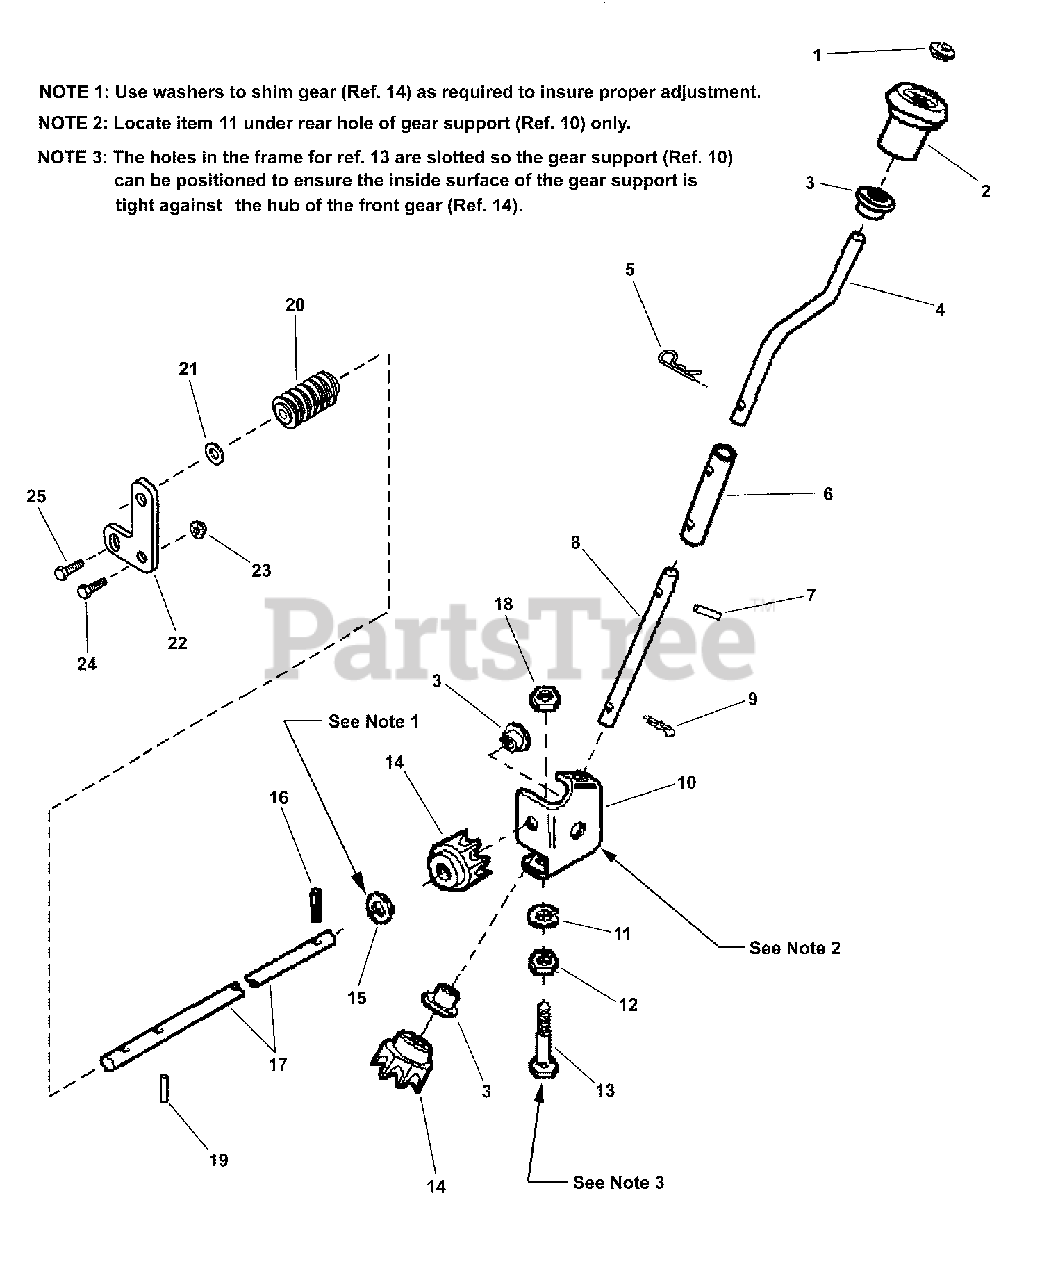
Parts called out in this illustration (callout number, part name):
1	PUSH NUT, Pal. .375 Dia. Stud Cap
2	KNOB, Spinner
3	BUSHING, .376 x .437 x .20
4	ROD, Chute, Upper
5	CLIP, .093 Dia. Hair Pin
6	SPLICE, Chute Handle
7	SPRING PIN, .156 x 1.000
8	ROD, Chute Lower
9	COTTER PIN, .125 x 1.00
10	BRACKET, Universal Gear
11	WASHER, .250 (.27 ID x .62 OD)
12	RETAINER, 1/4" Bolt
13	BOLT, 1/4-20 x 5/8" Short Square Neck Carriage
14	GEAR, Universal
15	WASHER, 3/8" Flat- Black
16	SPRING PIN, .125 x .750
17	WORM SHAFT
18	NUT, 1/4-20 Hex Flange Lock
19	ROLL PIN, 1/8 x 3/4"
20	WORM
21	WASHER, .44 x .78 x .025 Curved
22	BRACKET, Worm
23	NUT, 5/16-18 Hex Flange Lock
24	SCREW, 5/16-18 x 5/8" Hex Head Cap, GR 5
25	SCREW, 1/4-20 x 1/2" Hex Washer Self-Tap
